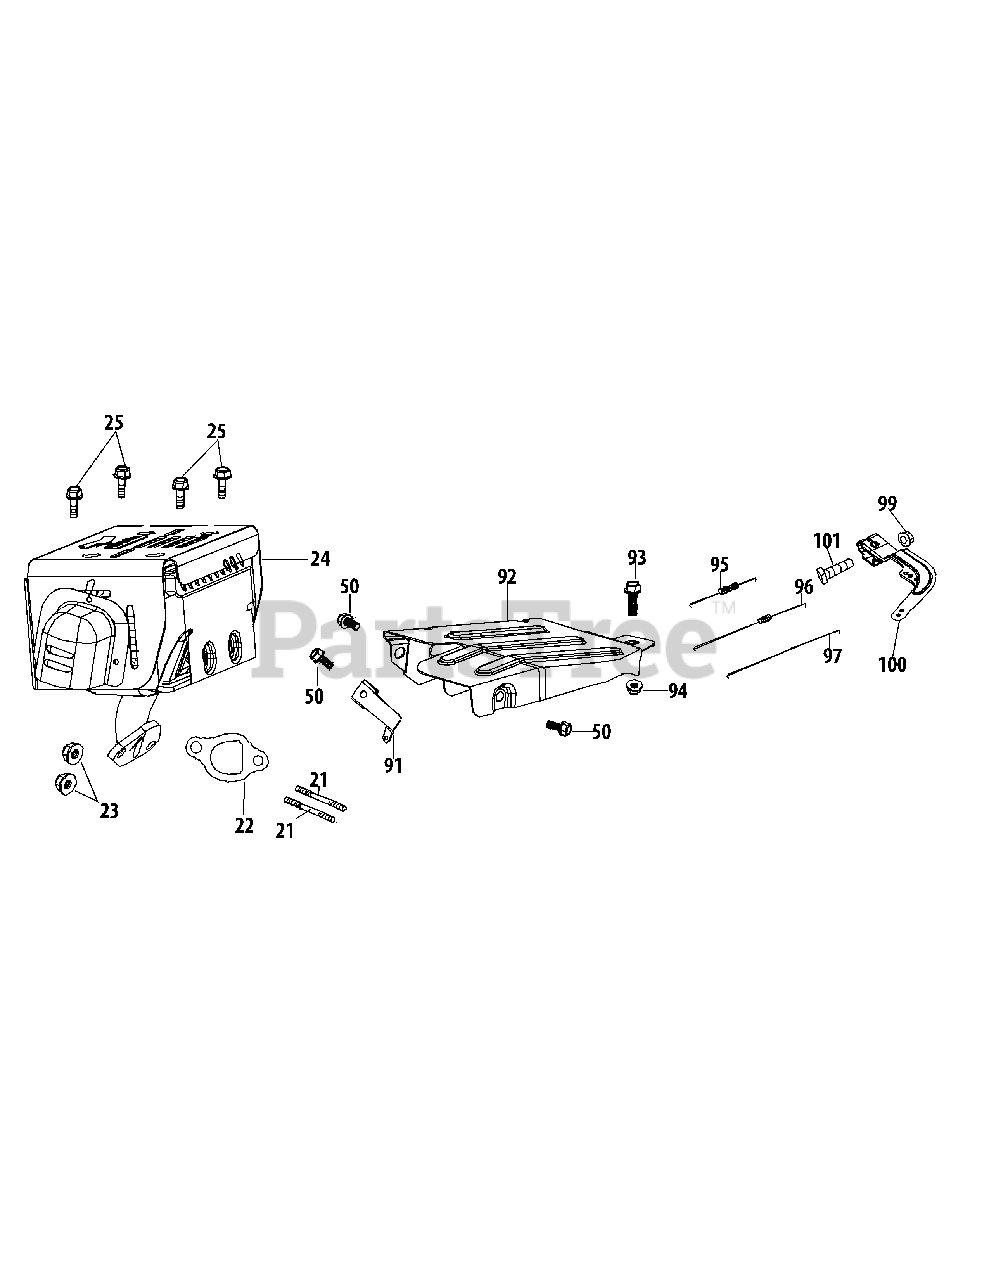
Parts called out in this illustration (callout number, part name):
21	Stud M8×34
21	Muffler Stud Assembly
22	Exhaust Pipe Gasket
24	Muffler Assembly
25	Bolt M5×10
50	Bolt M6×12
91	Governor Spring Bracket
92	Governor Shield
93	Bolt M6×28
95	Governor Spring
96	Throttle Linkage Spring
97	Throttle Linkage
99	Nut M6
100	Governor Arm
101	Governor Arm Bolt
